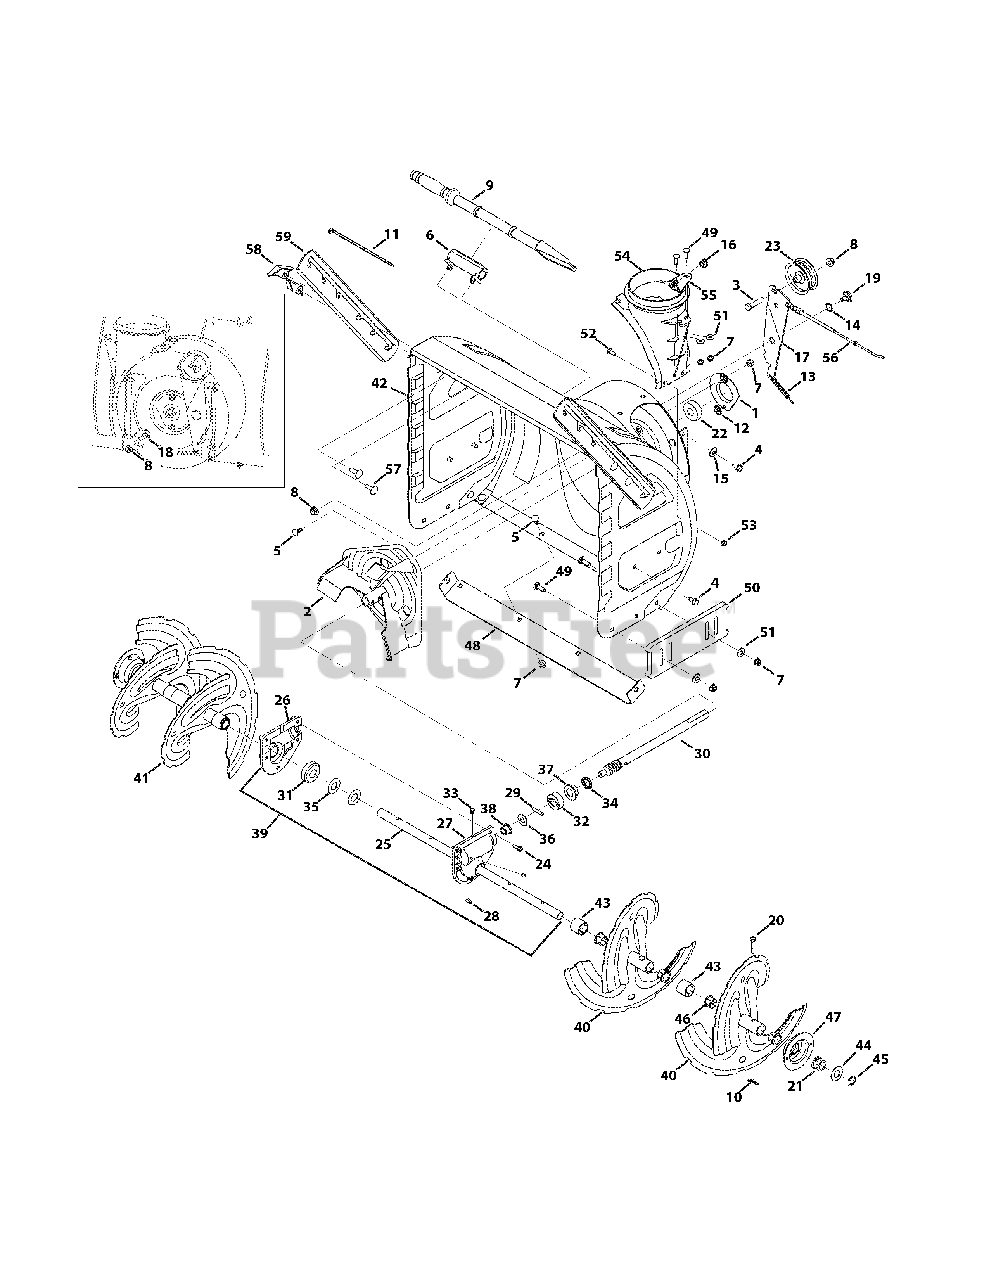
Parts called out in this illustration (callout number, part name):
1	Bearing Housing, 1.85 ID
2	Impeller Assembly, 12" Dia.
3	Hex Screw, 3/8-16 x 1.75
4	Taptite Screw, 5/16-18 x .750
5	Carriage Bolt, 5/16-18 x .75, Grade 5
6	Cleanout Tool Mount
7	Flange Lock Nut, 5/16-18
8	Flange Lock Nut, 3/8-16
9	Cleanout Tool
10	Bow-Tie Cotter Pin
11	Cable Tie
12	Push-On Nut, .25 Dia.
13	Extension Spring, .38 OD x 4.59
14	Wave Washer, .625 x .885 x .0175
15	Washer, Bell, .340 x .872 x .060
16	Plastic Bushing, .380 ID
17	Auger Idler Bracket
18	Shoulder Bolt, 3/8-16 x .496 x .336
19	Shoulder Screw, 3/8-16 x .625 x .17
20	Shear Pin, .25 x 1.50
21	Hex Flange Bearing
22	Flange Ball Bearing, .75 ID x 1.85 OD
23	Flat Pulley, 2.75 OD
24	Taptite Screw, 1/4-20 x .750
26	Housing Assembly, RH
27	Housing Assembly, LH
28	Hi-Pro Key, 3/16 x 5/8
29	Dowel Pin, .25OD x 1.25
30	Worm Shaft, .75 OD
31	Worm Gear, 20T
32	Thrust Collar, .756 ID x .600
33	Plug, 1/4 x .437
34	Oil Seal, .75 x 1.131 x .188
35	Flat Washer, .760 ID x 1.50 OD
36	Flat Washer, .51 x 1.12 x .06
37	Flange Bearing, .75 ID x 1.0 OD x .59
38	Flange Bearing, .50 ID x .75 OD x .59
39	Gear Box; includes Ref. 24 - 38
40	Spiral Assembly (Left)
41	Spiral Assembly (Right)
42	Auger Housing, 24" Cub
43	Spacer, 1.25OD x .75ID x 1.00
44	Flat washer, .76 x 1.49 x .06
45	E-Ring, .750
46	Flange Bushing, .800 ID x .910 OD
47	Hex Bearing Housing
48	Shave Plate, 24"
49	Screw, Carriage, 5/16-18 x 1.00
50	Deluxe Shoe
51	Washer, Flat, .349 x .879 x .063
52	Carriage Screw, 1/4-20 x .75
53	Flange Lock Nut, 1/4-20
54	Chute Adapter, 5"
55	Chute Crank Bracket
56	Auger Drive Cable
57	Carriage Bolt, 5/16-18 x .875
58	Wing Knob, 5/16-18
59	Drift Cutter
